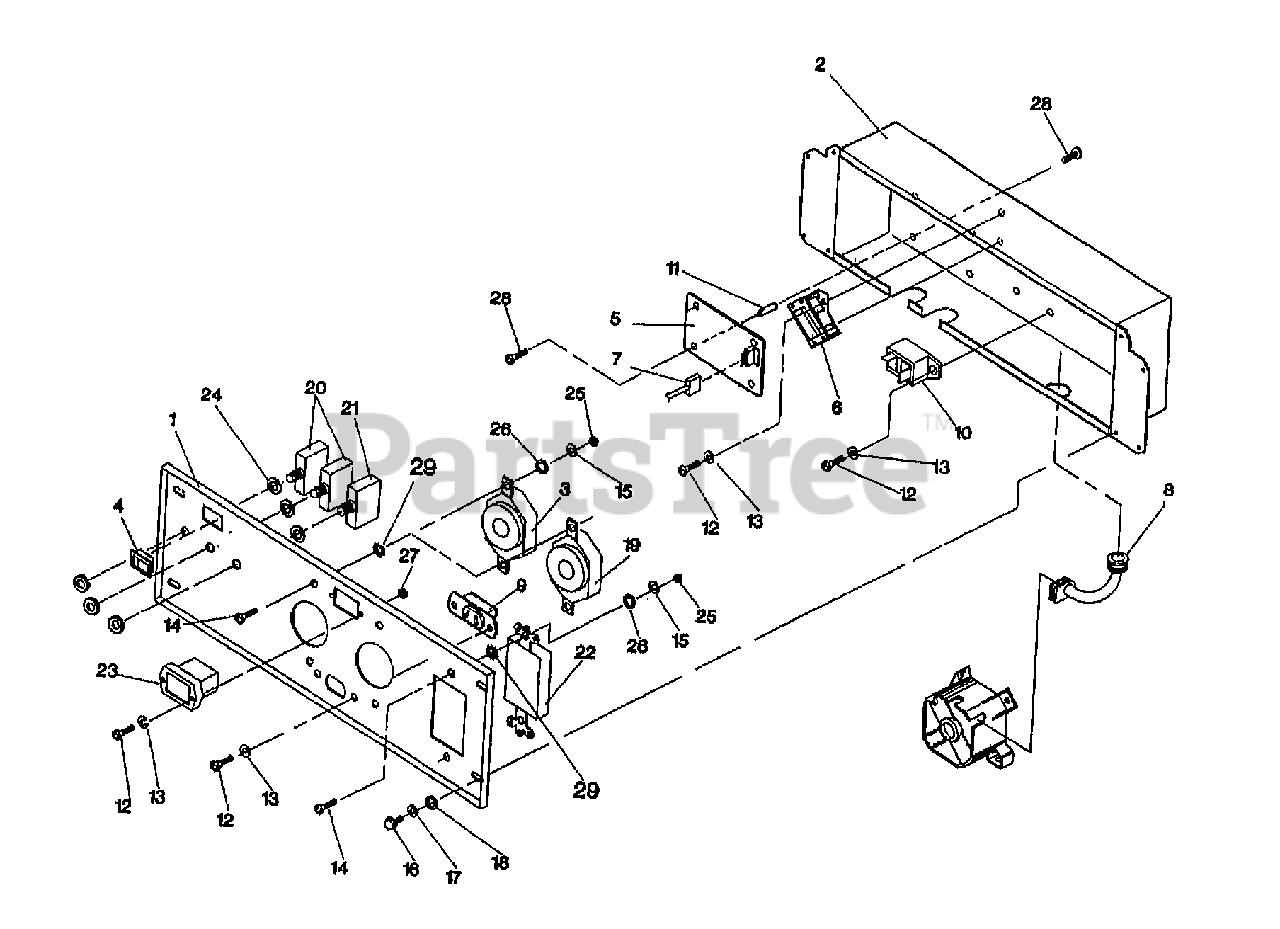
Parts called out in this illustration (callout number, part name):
1	PANEL-CONTROL (6000W GEN)
2	BOX-CONTROL PANEL (6000W GEN)
3	OUTLET-120V 20A (6000W GEN)
4	SWITCH-IDLE CONTROL (GENERATOR
5	BOARD-SYSTEM CONTROL (GENERATO
6	TRANSFORMER-IDLE CONTROL (GEN)
7	ASSM-WIRE HARNESS (GENERATOR)
8	CONNECTOR-RUBBER GROMMET (GEN)
9	BRKT&OUTLET-12V DC (GEN)
10	CIRCUIT BREAKER-12V 10A (GEN)
11	STAND-OFF HEX 3/4" LONG (GEN)
12	SCR-PH M3-.5X10MM
13	WASHER-LOCK M3 (GEN)
14	SCR-PH M4-.7X10MM
15	WASHER-LOCK M4 (GEN)
16	SCR-PH M5-.8X12MM
17	WASHER-LOCK M5 (GEN)
18	WASHER-LOCK M5 (GEN)
19	OUTLET-120V 30A
20	CIRCUIT BREAKER-30A (GEN)
21	CIRCUIT BREAKER-20A (GEN)
22	OUTLET-DUPLEX GFCI 120V 20A (G
23	METER-HOUR (GENERATOR)
24	WASHER-LOCK INTERNAL
25	NUT-HEX M4-0.7 (GEN)
26	WASHER-FLAT M4
27	NUT-HEX M3-0.5 (GENERATOR)
28	SCR-SELF TAP #6-32 X 3/8 (GEN)
29	WASHER-LK #8 (GENERATOR)
